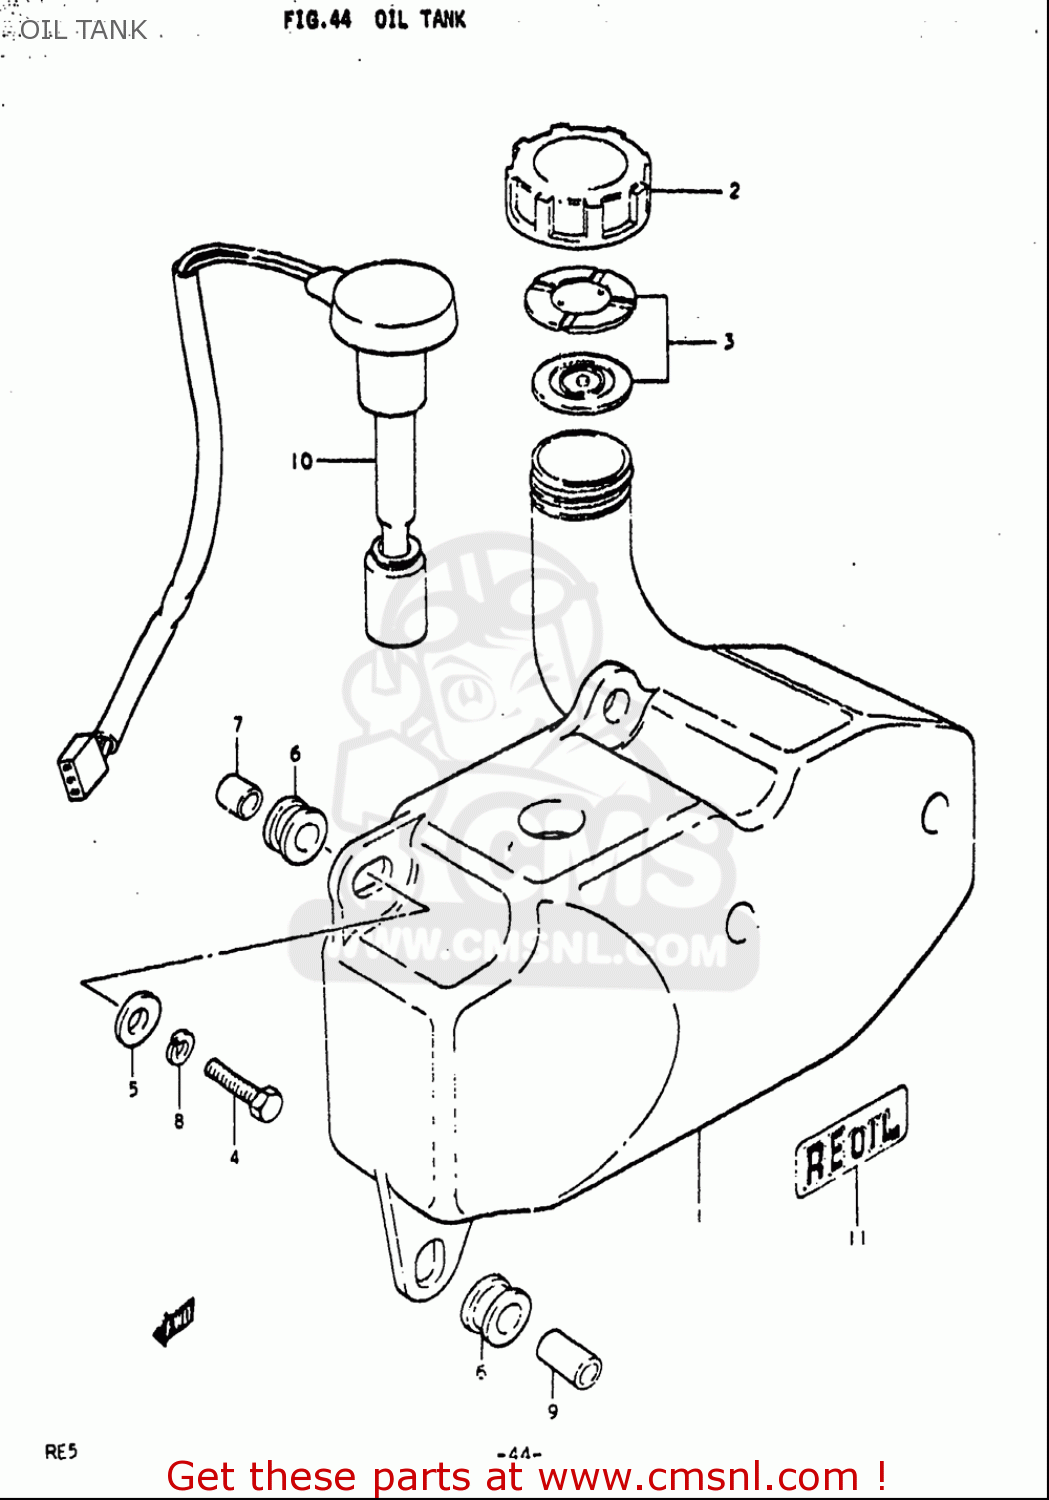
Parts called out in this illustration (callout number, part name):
2	CAP,OIL TANK
3	GASKET SET (NAS)
4	BOLT 6X23
5	WASHER(6.5X18X1.6)
6	CUSHION
7	SPACER(6.5X10X10)
8	WASHER,LOCK
9	SPACER(6.4X10X18)
